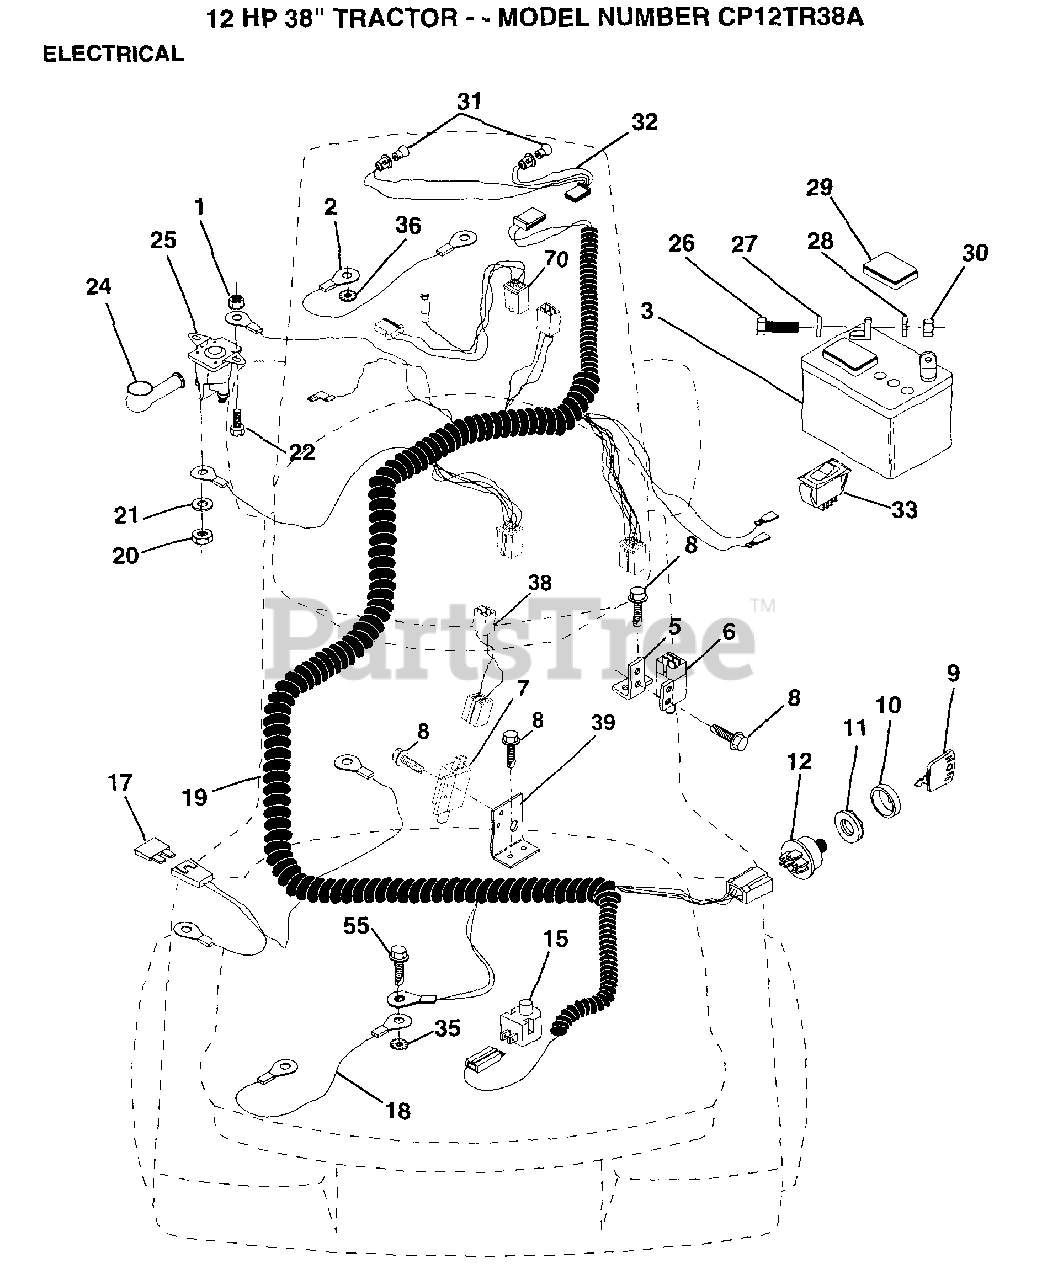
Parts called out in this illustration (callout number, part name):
1	NUT
5	BRACKET LT
6	SWITCH INTERLOCKT
7	SWITCH-INTER. GT
8	SCREW
9	KEY STEEL DELTA
10	COVER KEY SWITCH
15	SWITCH SEAT
17	FUSE HYT
18	CABLE ASSY
19	HARNESS.IGN.FEND.
20	NUT
22	BOLT
26	BOLT LT
27	WASHER
28	LOCKWASHER
29	"CAP,BATTERY "
31	HEADLAMP BULB
32	"HARNESS,LIGHT SOC"
33	SWITCH LT
35	LOCKWASHER.5/16.E
36	LOCKWASHER
38	ADAPTER.HARN.SERV
39	BRACKET SWT CLUTC
55	SCREW LT
70	HARNESS ENG DUAL
